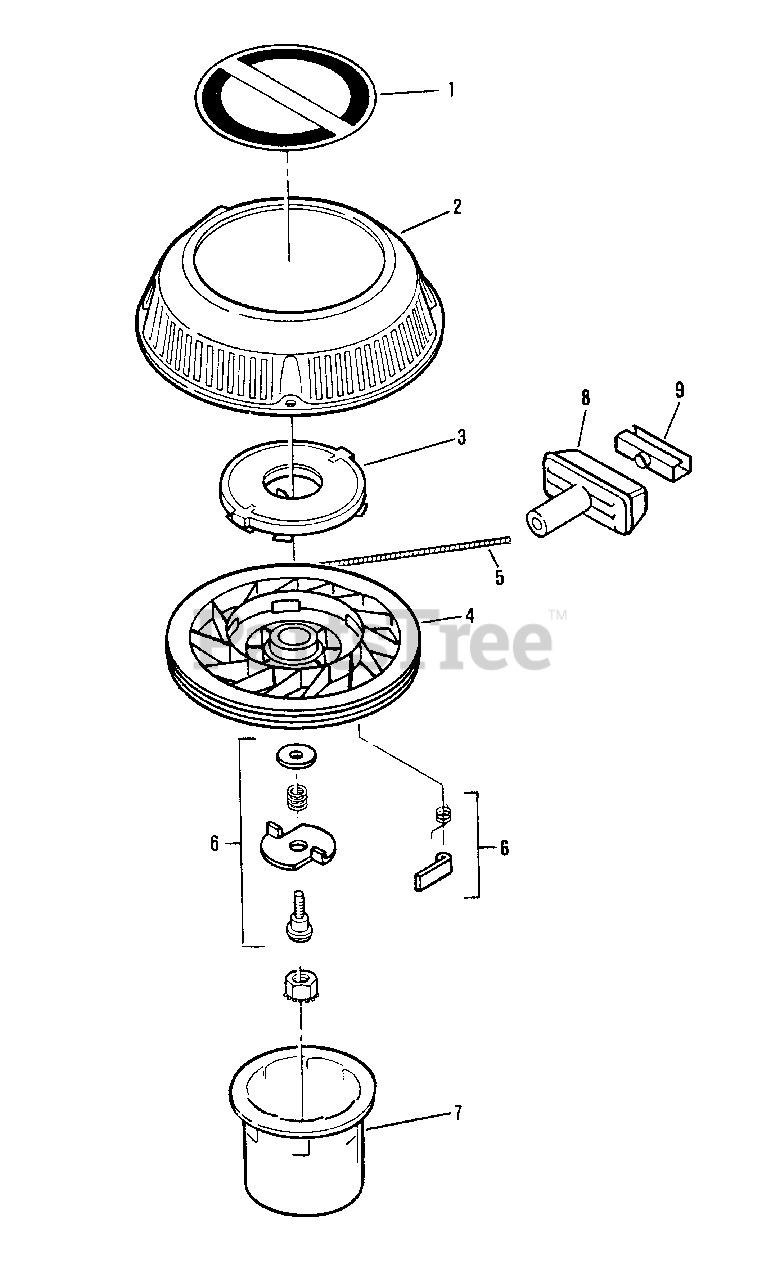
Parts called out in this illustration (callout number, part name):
1	Decal
2	Starter Housing and Shaft Assembly
3	Recoil Spring and Keeper Assembly
4	Pulley
5	Rope
6	Dog Kit Assembly
7	Starter Hub
8	Handle-Starter
9	Clip-Starter Handle
